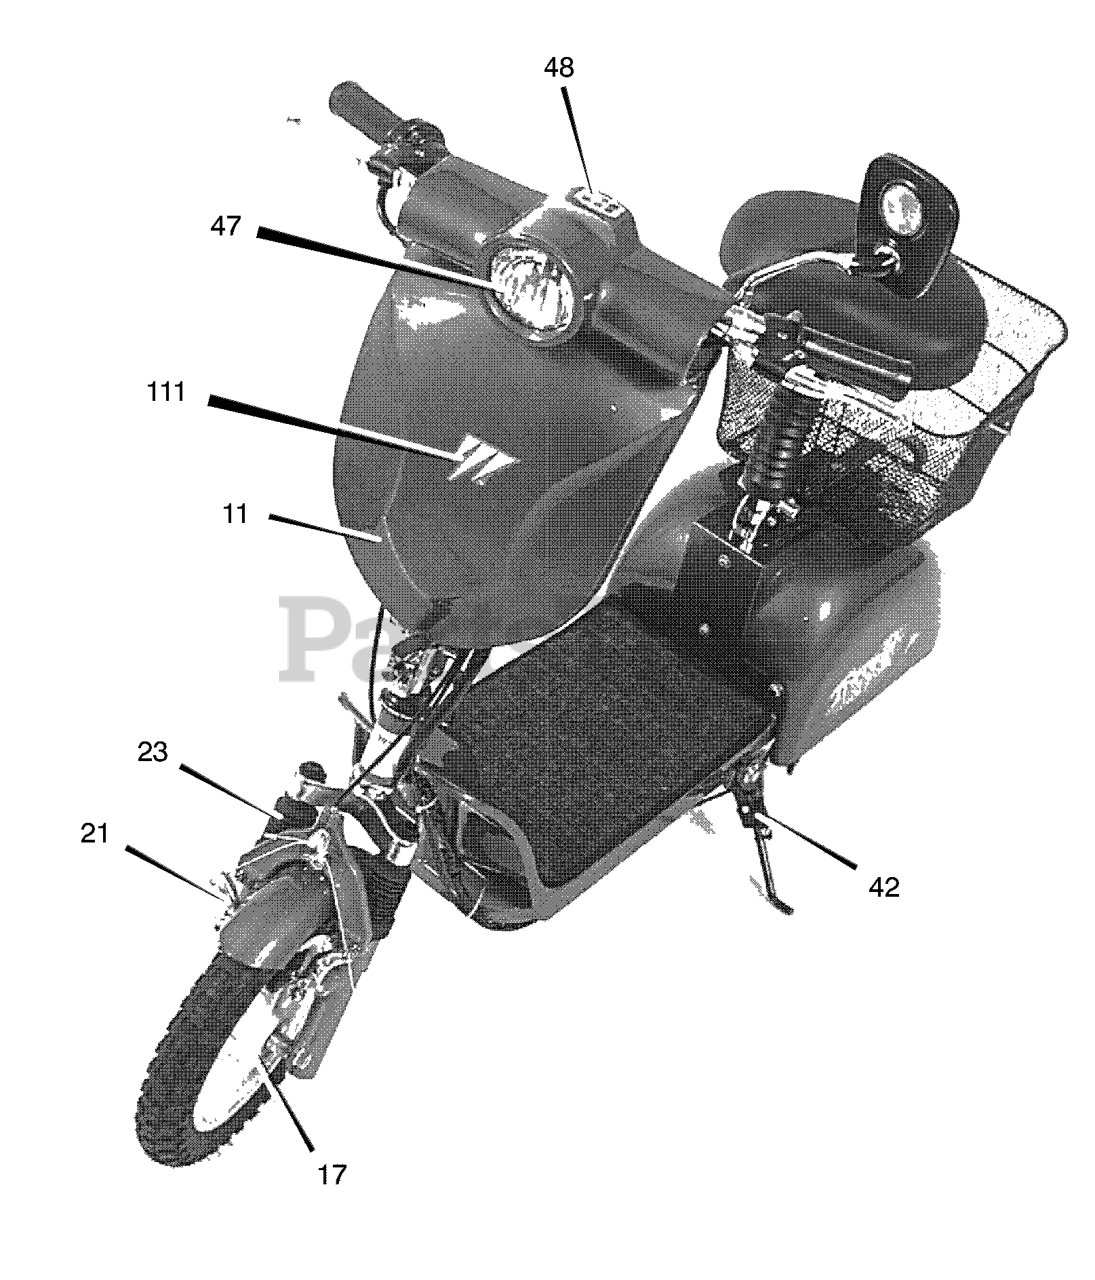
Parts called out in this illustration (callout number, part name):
11	Cover, Front Handlebar (with battery indicater decal (PN 7201124)
17	Wheel & Axle Assembly - Front
21	Fender, Front (RED)
23	Fork, Suspension
42	Kickstand Ass'y-with Spring
47	Headlight Assembly (12V)
48	Circuit Board, Battery Indicator
111	Decal, Murray Logo
